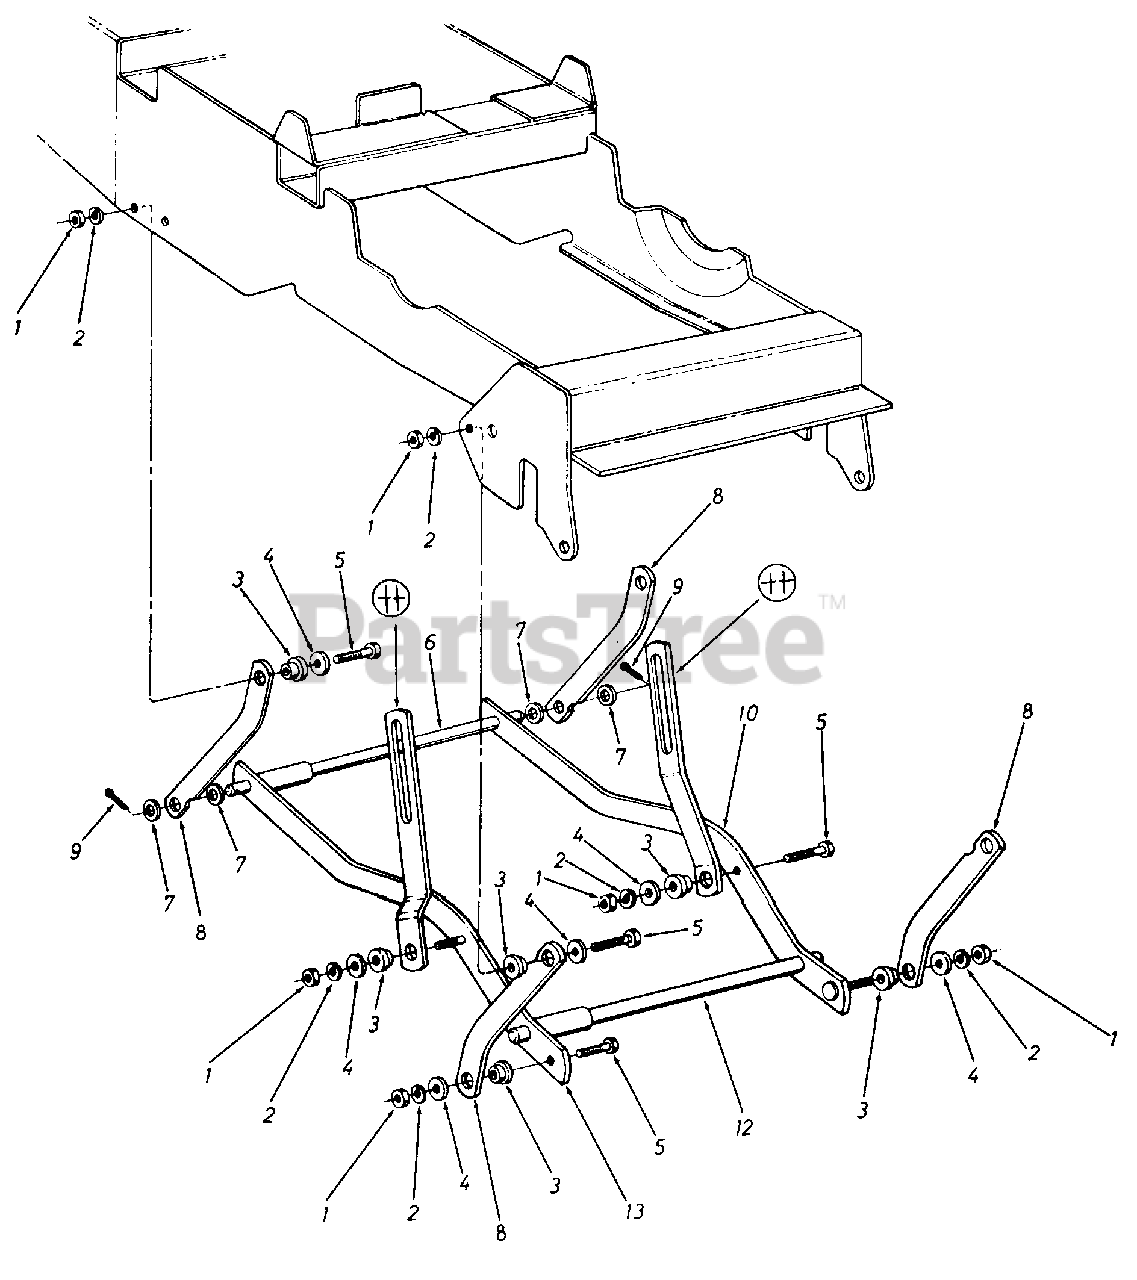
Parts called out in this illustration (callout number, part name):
1	Hex Nut 3/8-24 Thd.*
2	L.-Wash. 3/8" Scr. Heavy Duty
3	Shoulder Spacer
4	Fl.-Wash. 3/8"1.D. x 1.0" O.D.
5	Hex Scr. 3/8-24 x 1.50" Lg. Grade 5
6	Cross Shaft Ass'y.-Rear
7	Fl.-Wash. 5/8" I.D. x 1-1/8" 0.D.
8	Lift Arm
9	Cotter Pin 5/32" Dia. x 1.25" Lg.
10	LiftArm LinkAss'y.-L.H.
12	Cross Shaft Ass'y.-Front
13	Lift Arm Link Ass'y.-R.H.
